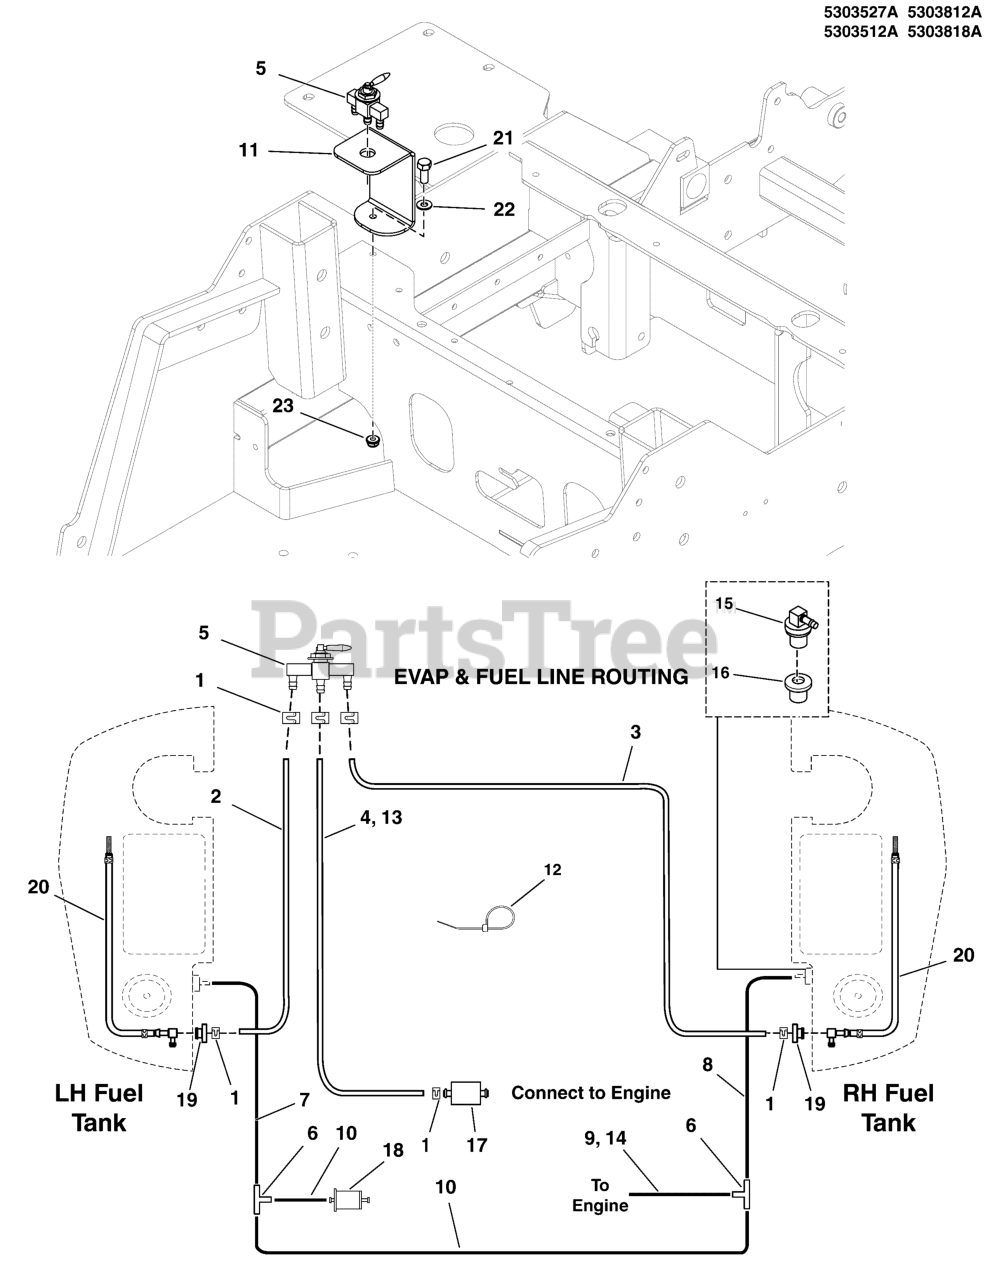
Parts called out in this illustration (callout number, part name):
1	CLAMP, Hose
2	1/4" Fuel Line, 11" Long
3	HOSE, 1/4" FUEL, 27.00"
4	HOSE, 1/4" FUEL, 19.50"
5	VALVE, FUEL STRAIGHT, OUTLET
6	FITTING, 3/16" TEE, BARB TYPE, HDPE
7	HOSE, VAPOR, 5MM ID, 15.50 LG
8	HOSE, VAPOR, 5MM ID, 23.00 LG
9	HOSE, VAPOR, 5MM ID, 32.00 LG
10	HOSE-VAPOR
11	MOUNT, FUEL VALVE, 2100Z - BLK
12	TIE, SELF-LOCKING, 6"
13	HOSE, FUEL, 1/4 IN, LW PRMTN, 16" LONG
14	HOSE, VAPOR, 5MM ID, 13.50 LG
15	REMOTE VENT ASSEMBLY
16	GROMMET (SV)
17	FUEL FILTER (SV)
18	FILTER, FUEL
19	BUSHING-FUEL TANK RED RUBBER
20	PICKUP TUBE ASSEMBLY, FUEL LINE (SV)
21	BOLT, 5/16-18 X 3/4 GD5
22	WASHER, 5/16" SAE
23	NUT, 5/16-18 HEX NYLOCK FLANGE NUT
